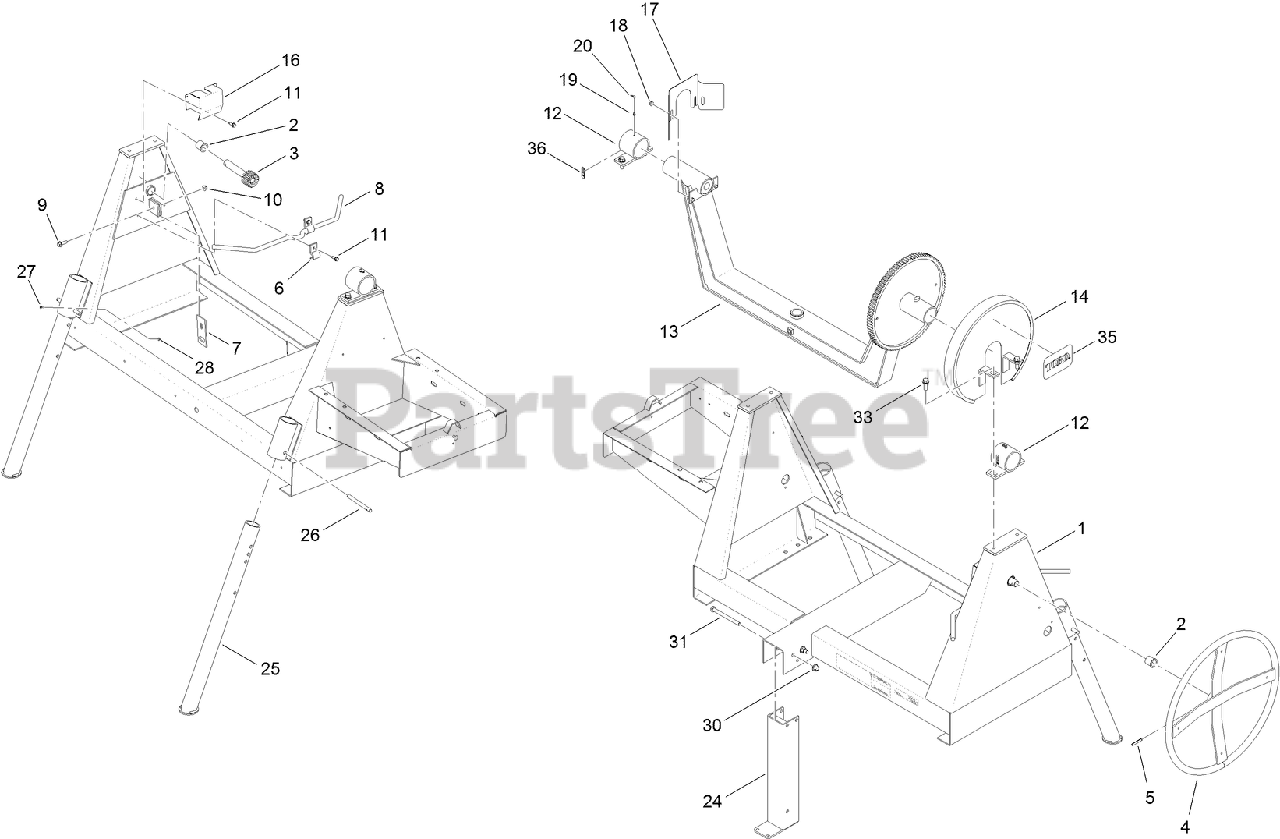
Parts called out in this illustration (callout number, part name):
2	BUSHING-NYLON
3	SHAFT-TILT
4	HANDWHEEL
5	PIN-ROLL
6	BRACKET-HANDLE
7	DOG-BRAKE
8	HANDLE-BRAKE
9	SCREW-HHF
10	NUT-HF, NI
11	SCREW-HWHTF
12	TRUNNION
13	YOKE ASM
14	GUARD-BRAKE, UPPER
16	GUARD-BRAKE, LOWER
17	GUARD-PINION
18	NUT-HF, NI
19	FITTING-GREASE
20	CAP-PLUG
24	POST-FOOT
25	LEG-STABILIZER
26	PIN-CLEVIS, LANYARD
27	SCREW-PPH
28	NUT-LOCK, NI
30	NUT-LOCK
31	SCREW-HH
33	SCREW-HWH
35	DECAL
36	DECAL-GREASE
